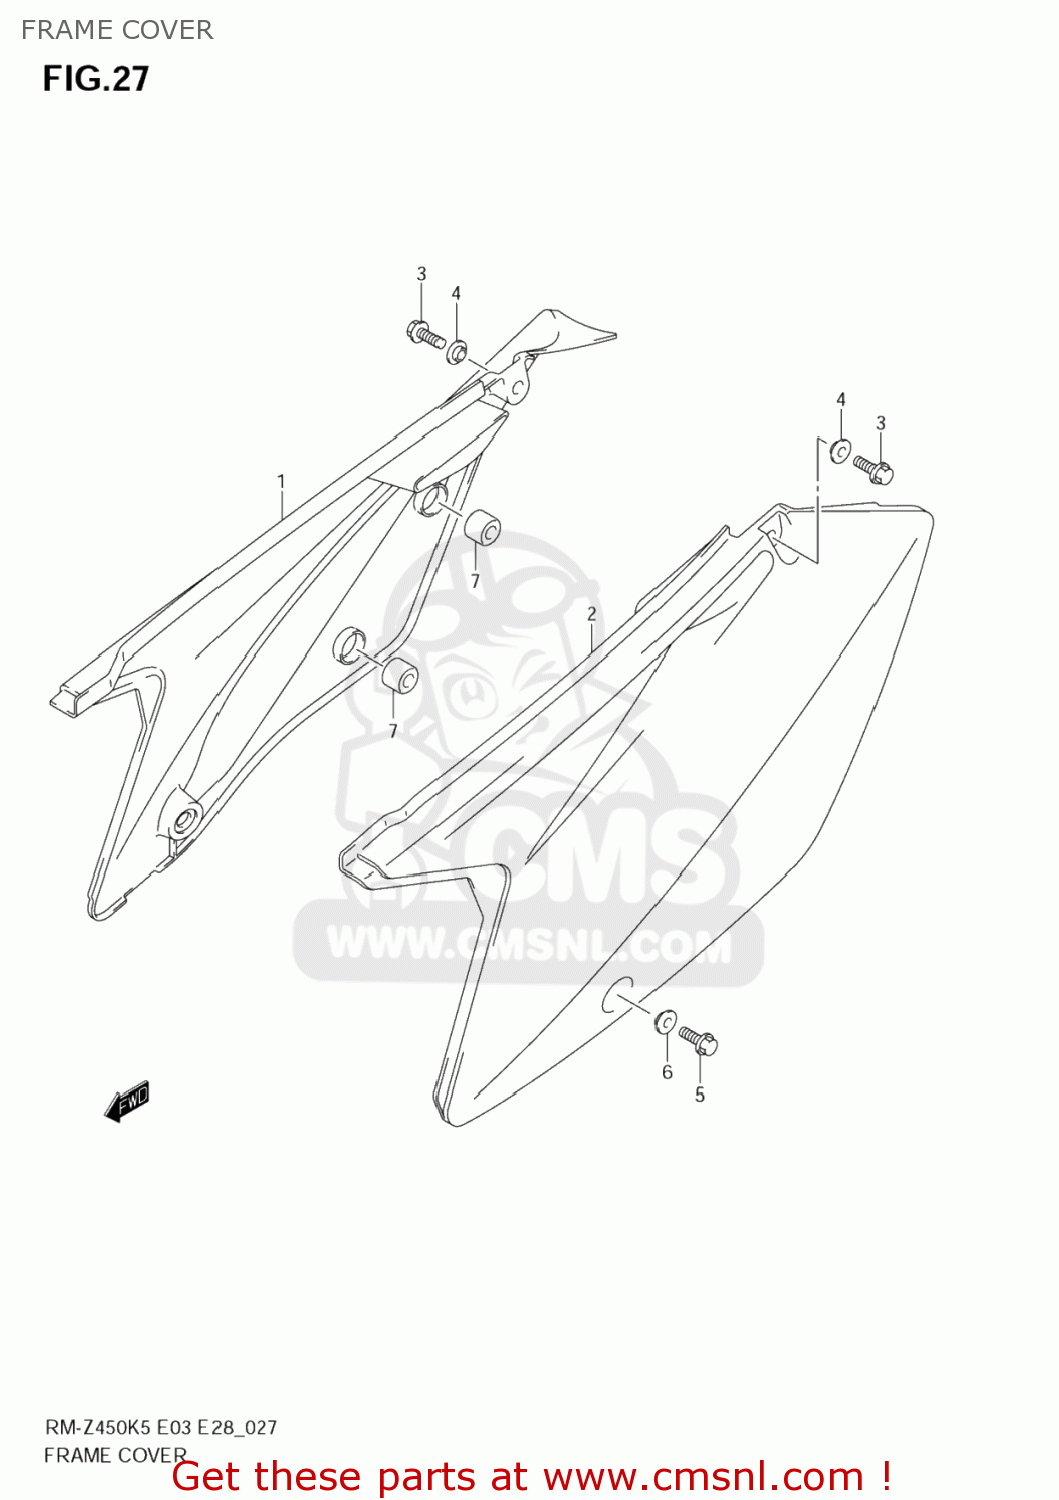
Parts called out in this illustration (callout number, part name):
1	COVER,FRAME,R(WHITE)
2	COVER,FRAME,L(WHITE)
3	BOLT(6X16)
4	WASHER,RR BRAK
5	BOLT(6X16)
6	WASHER,RR BRAK
7	CUSHION,FRAME COVER,R
